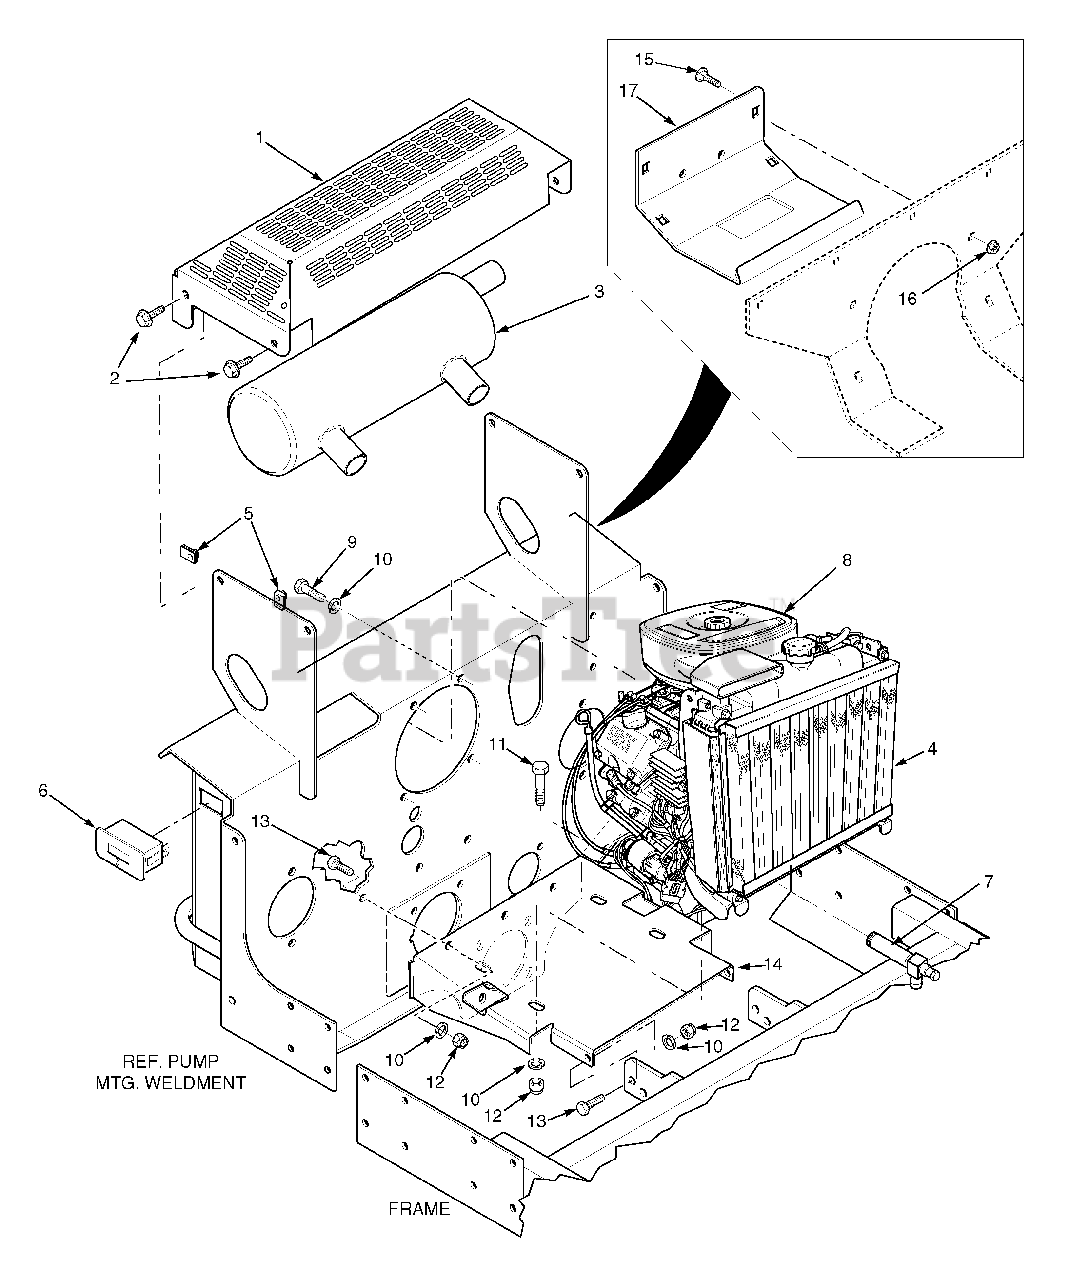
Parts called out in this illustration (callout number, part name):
1	Muffler Guard
2	Screw, Hex Serrated Flange 1/4-20 x 3/4"
3	Muffler
4	Screen Weldment, Radiator
5	U-Nut, 1/4-20
6	Hour Meter
7	Oil Drain, 2.6"
8	Engine, Kawasaki 27KA
9	Bolt, M10-1.50 x 25 Grade 8.8
10	Lockwasher, 3/8" Spring
11	Bolt, Hex Head 3/8-16 x 1-3/4"
12	Nut, Hex Elastic Stop 3/8-16
13	Bolt, Hex Head 3/8-16 x 1-1/4"
14	Plate, Engine Mounting
15	Bolt, Carriage 5/16-18 x 3/4"
16	Nut, Hex Serrated Flange 5/16-18
17	Rear Cover
